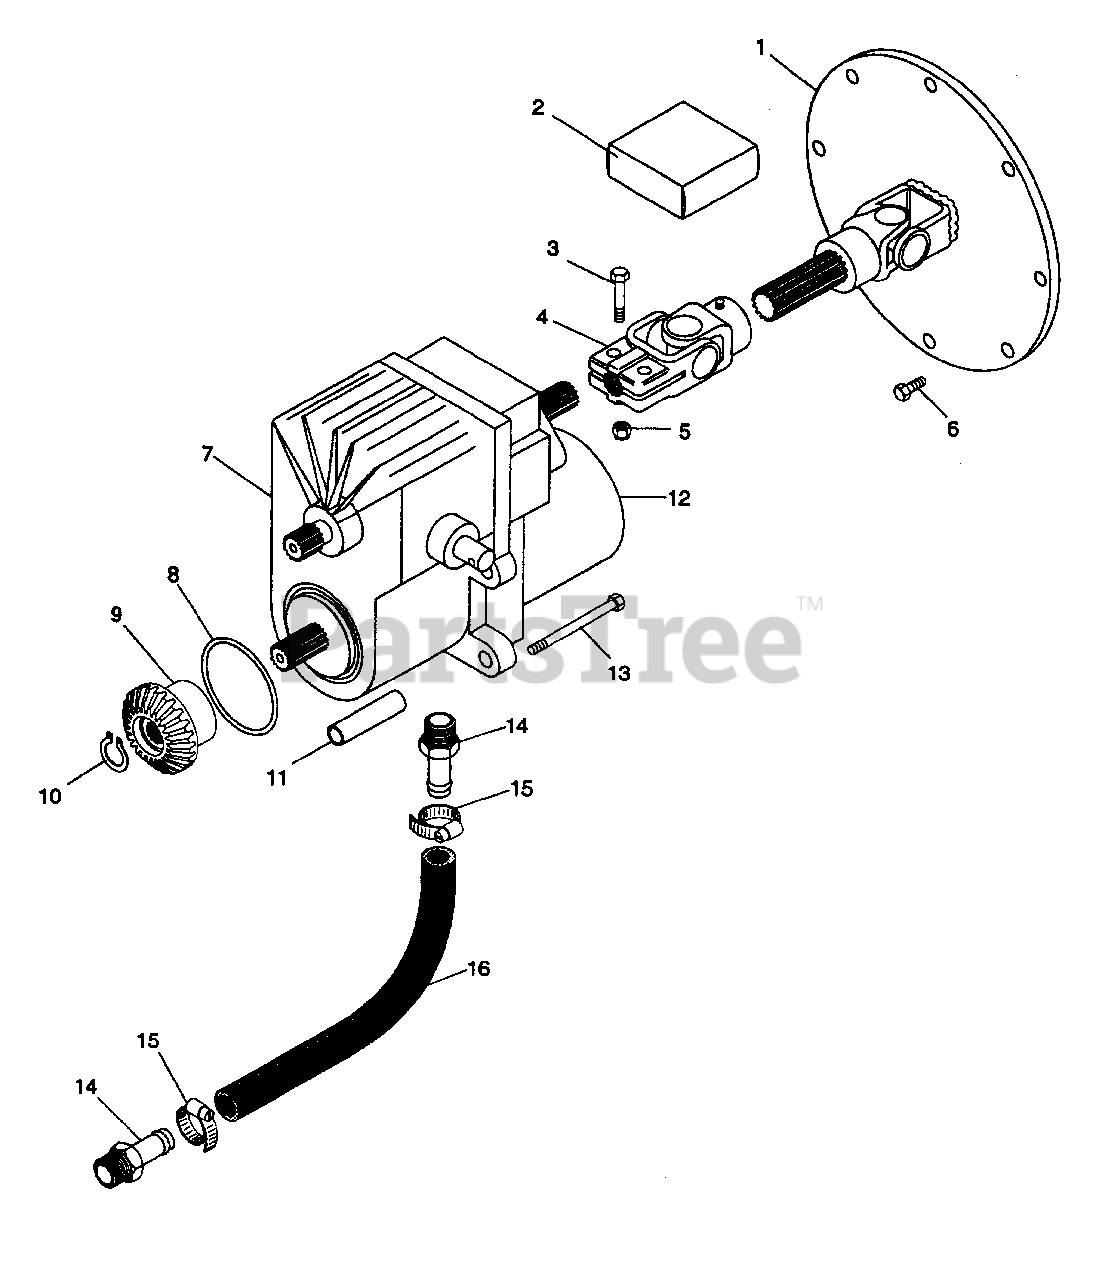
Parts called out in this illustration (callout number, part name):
1	ADPT, FLYWHEEL
2	KIT, U-JOINT REPAIR
3	BLT-HEX .38-16 X 1.75 PL GR 5
4	ASM, U-JOINT
5	NUT-LK-MYL .375-16 PI
6	BLT-HEX M8 X 1.25 X 20MM PI
7	TRANSMISSION, HYD
8	O-RING 3. X 3.187 X .093
10	RG-RTNG-EXT .579 X .93
11	BUSH., S .385 X .625 X 2.69 ST
12	OIL FILTER
13	BLT-HEX .88-16 X 4.00
14	FTG-ADPTR 88-14
15	CLAMP, .88 DIA. HOSE
16	HOSE
